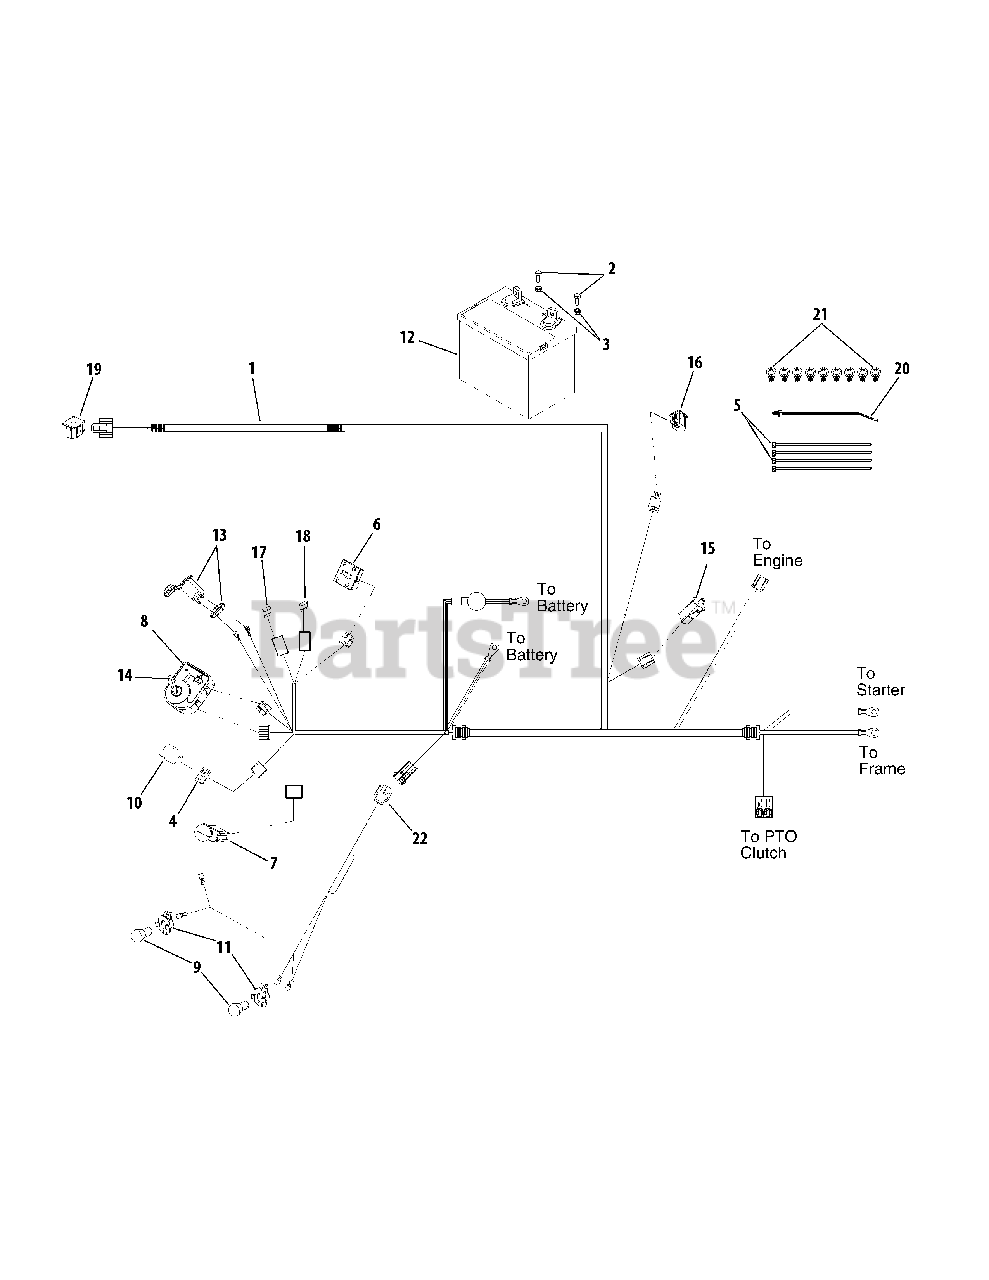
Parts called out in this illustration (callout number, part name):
1	Wire Harness, Main
2	Screw, Hex, 1/4-20 x .75 GR5
4	Gasket, Silicone
5	Tie, Self-Clinch Cable
6	Meter, Indicator / Hour
7	Switch, PTO
8	Switch, Key/Module
9	Lamp, Head Light
10	Relay
11	Socket, Light, 1/4 Turn
13	Receptacle, Power 12V
14	Key, Ignition
15	Switch, Interlock (Brake)
16	Switch, Snap Mount (Reverse)
17	Fuse, 25 Amp
18	Fuse, 5 Amp
19	Switch, Seat
20	Tie, Pushmount
21	Clip, Cable
22	Harness, Head Light
